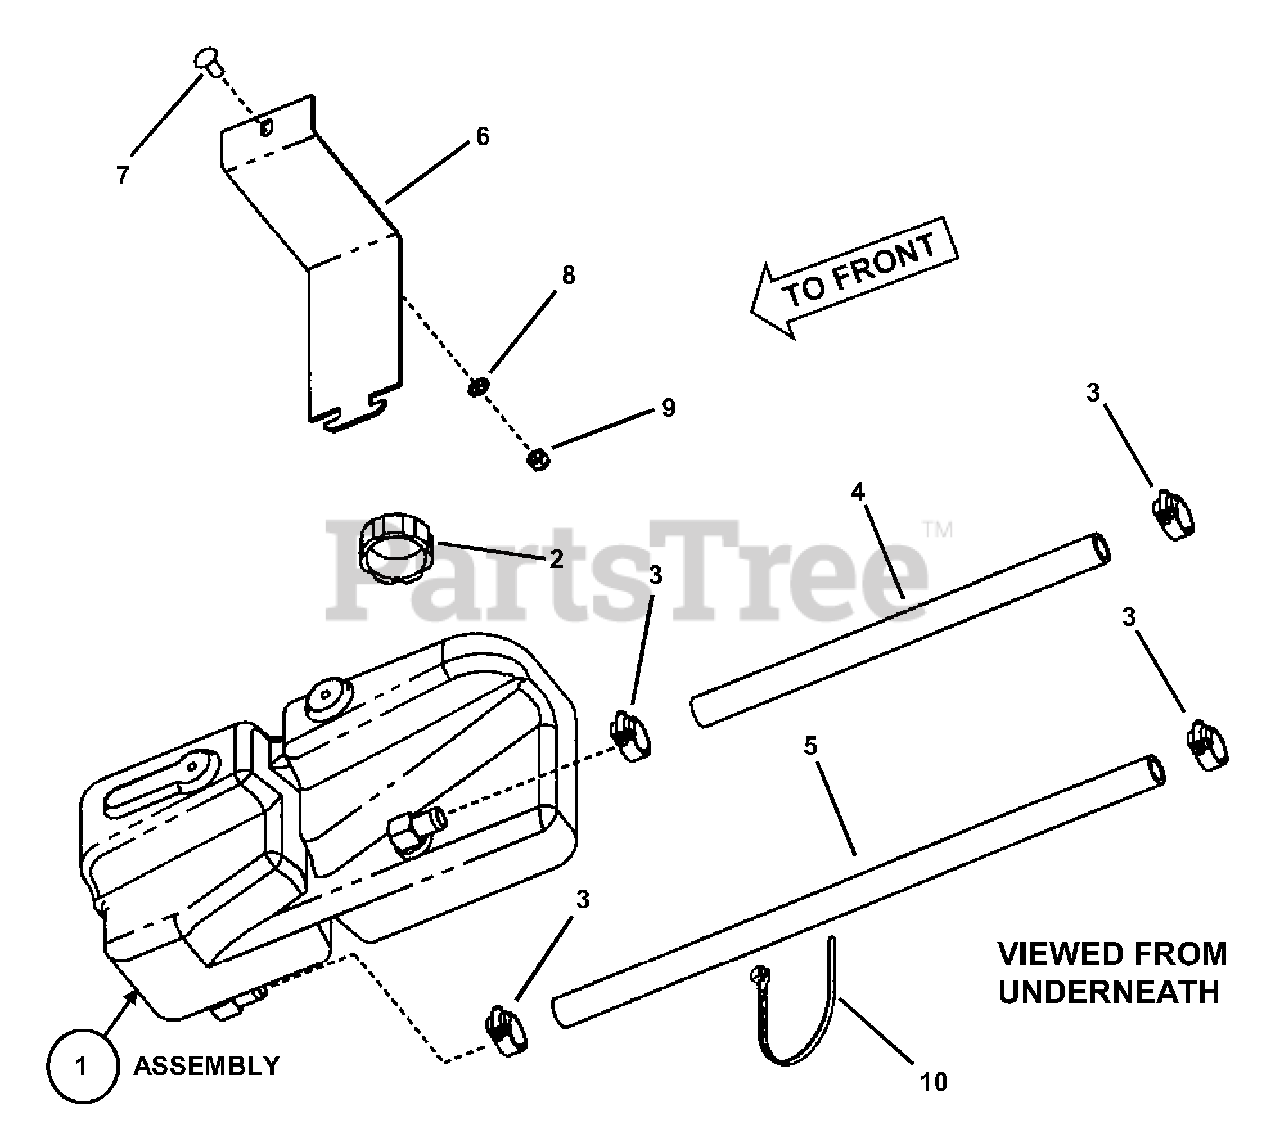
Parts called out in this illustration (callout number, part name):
1	RESERVOIR, L. H. Hydro
2	CAP, Reservoir
3	CLAMP,
4	HOSE, Rubber 5/8 I.D. x 13-1/2" long
5	HOSE, Rubber 5/8" I.D. x 20" long
6	BRACKET, Tank L. H.
7	BOLT, 5/16-18 x 3/4" Short Neck Carriage, Grade 5
8	RETAINER, 5/16" Bolt
9	NUT, 5/16-18 HEX NYLON LOCK
10	CABLE TIE, 7" long
